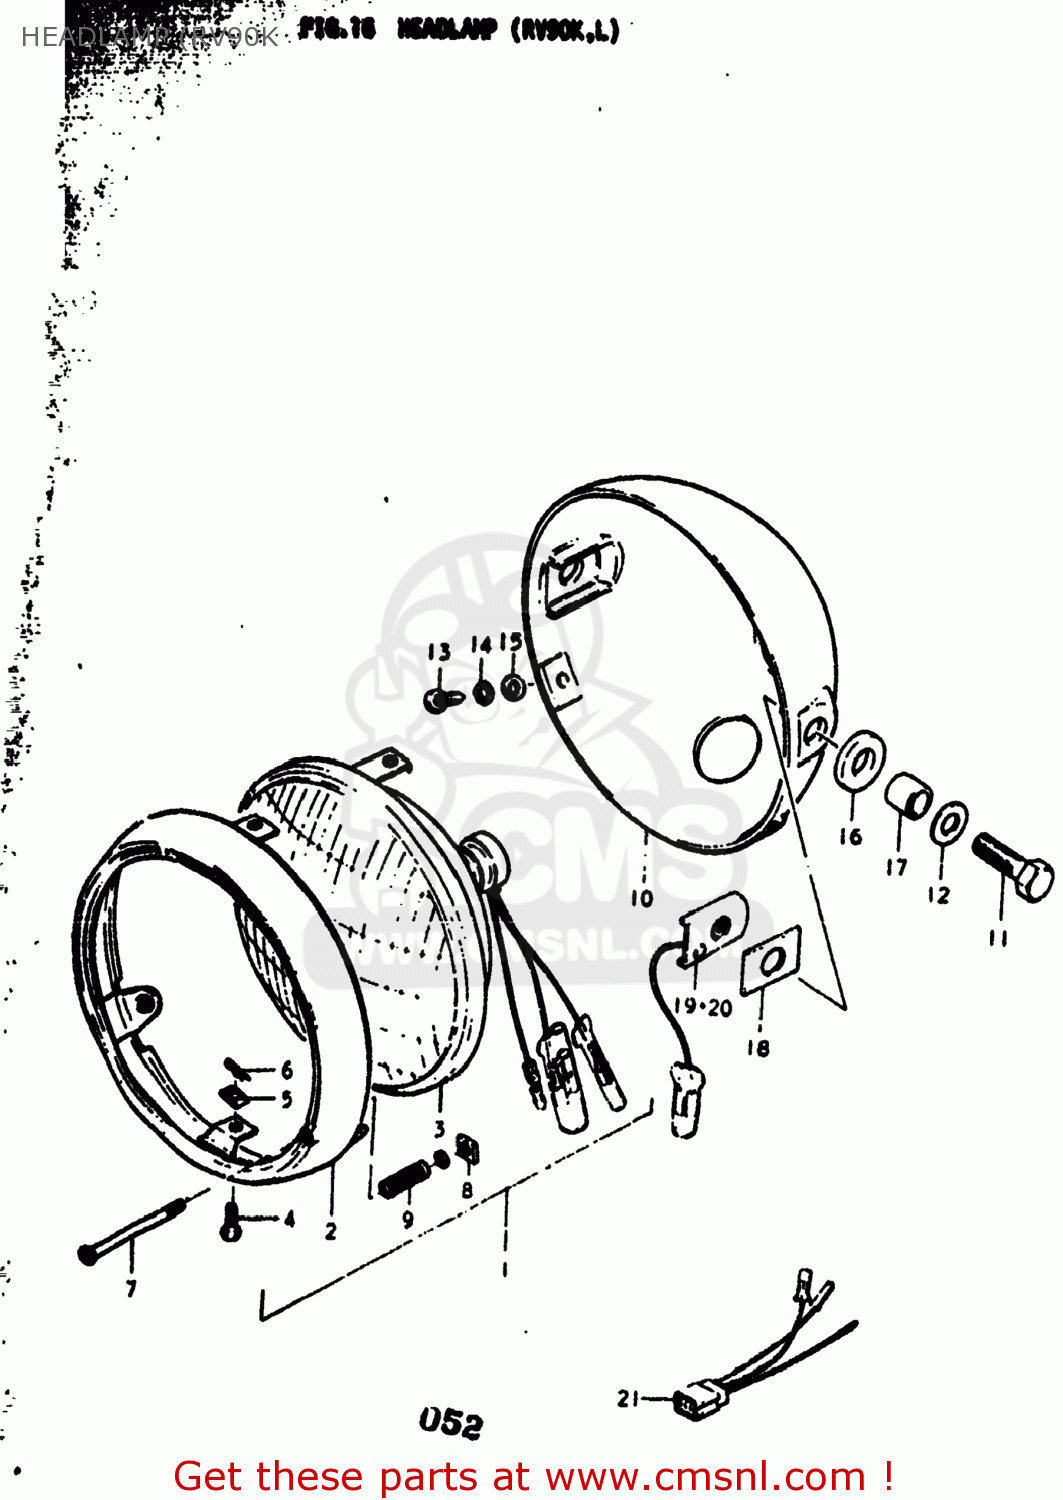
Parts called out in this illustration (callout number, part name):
1	HEADLAMP ASSEMBLY
2	RIM,HEADLAMP
3	LAMP UNIT
4	SCREW,LENS
5	NUT,ADJUSTING
6	CUSHION,HEADLAMP
7	SCREW,HEADLAMP ADJUST
8	NUT,HEADLAMP ADJUSTER
9	SPRING,HEADLAMP ADJUST
10	HOUSING COMP,HEADLAMP
11	BOLT
12	WASHER 8MM
13	SCREW
14	LOCK WASHER
15	WASHER
16	CUSHION
17	SPACER (8.8X12X11)
18	CUSHION
19	PLATE, RH K,L
20	PLATE,HEADLAMP HOUSING
